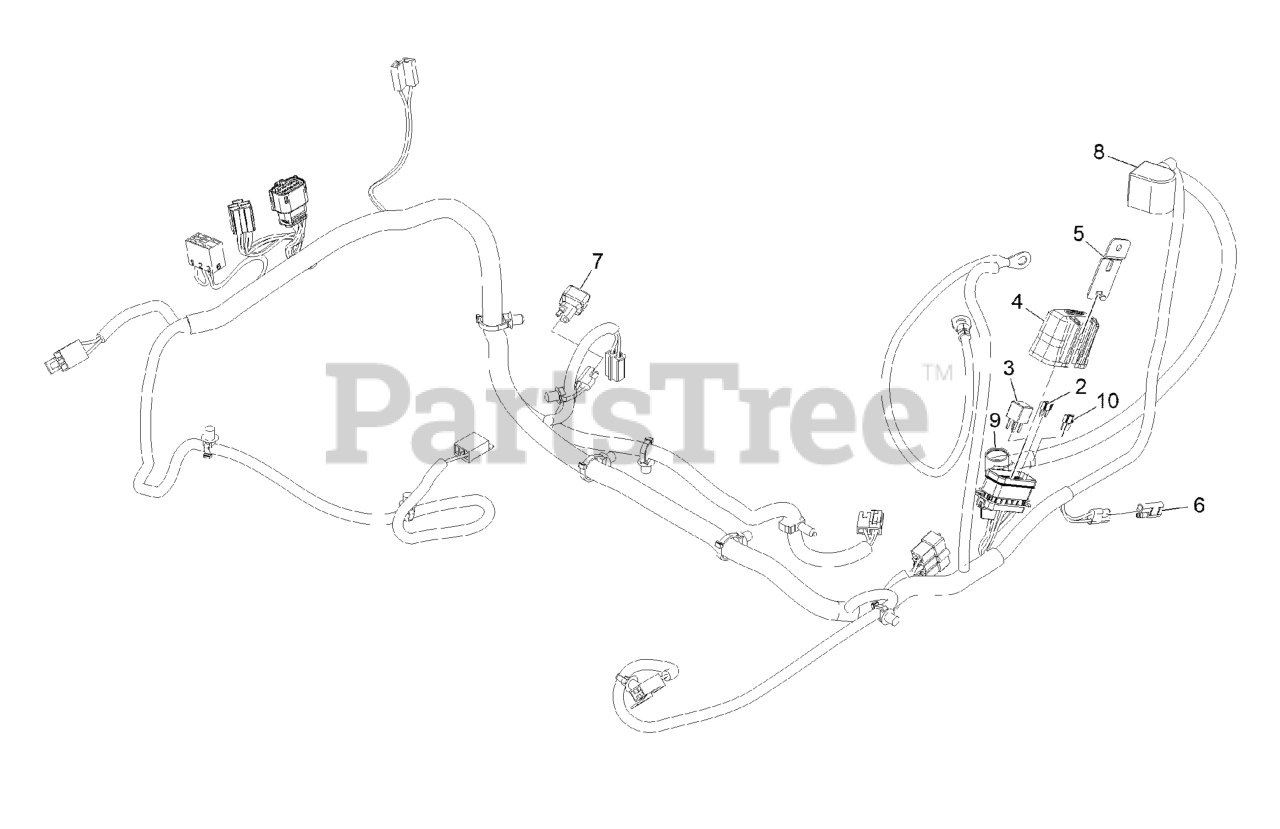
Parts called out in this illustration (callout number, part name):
2	FUSE-MINI BLADE, 20 AMP
3	RELAY-MICRO
4	COVER-BLOCK, FUSE
5	CLIP-MOUNTING
6	CAP-PLUG
8	INSULATOR-BATTERY
9	INSULATOR-SOLENOID
10	FUSE-MINI BLADE, 15 AMP
